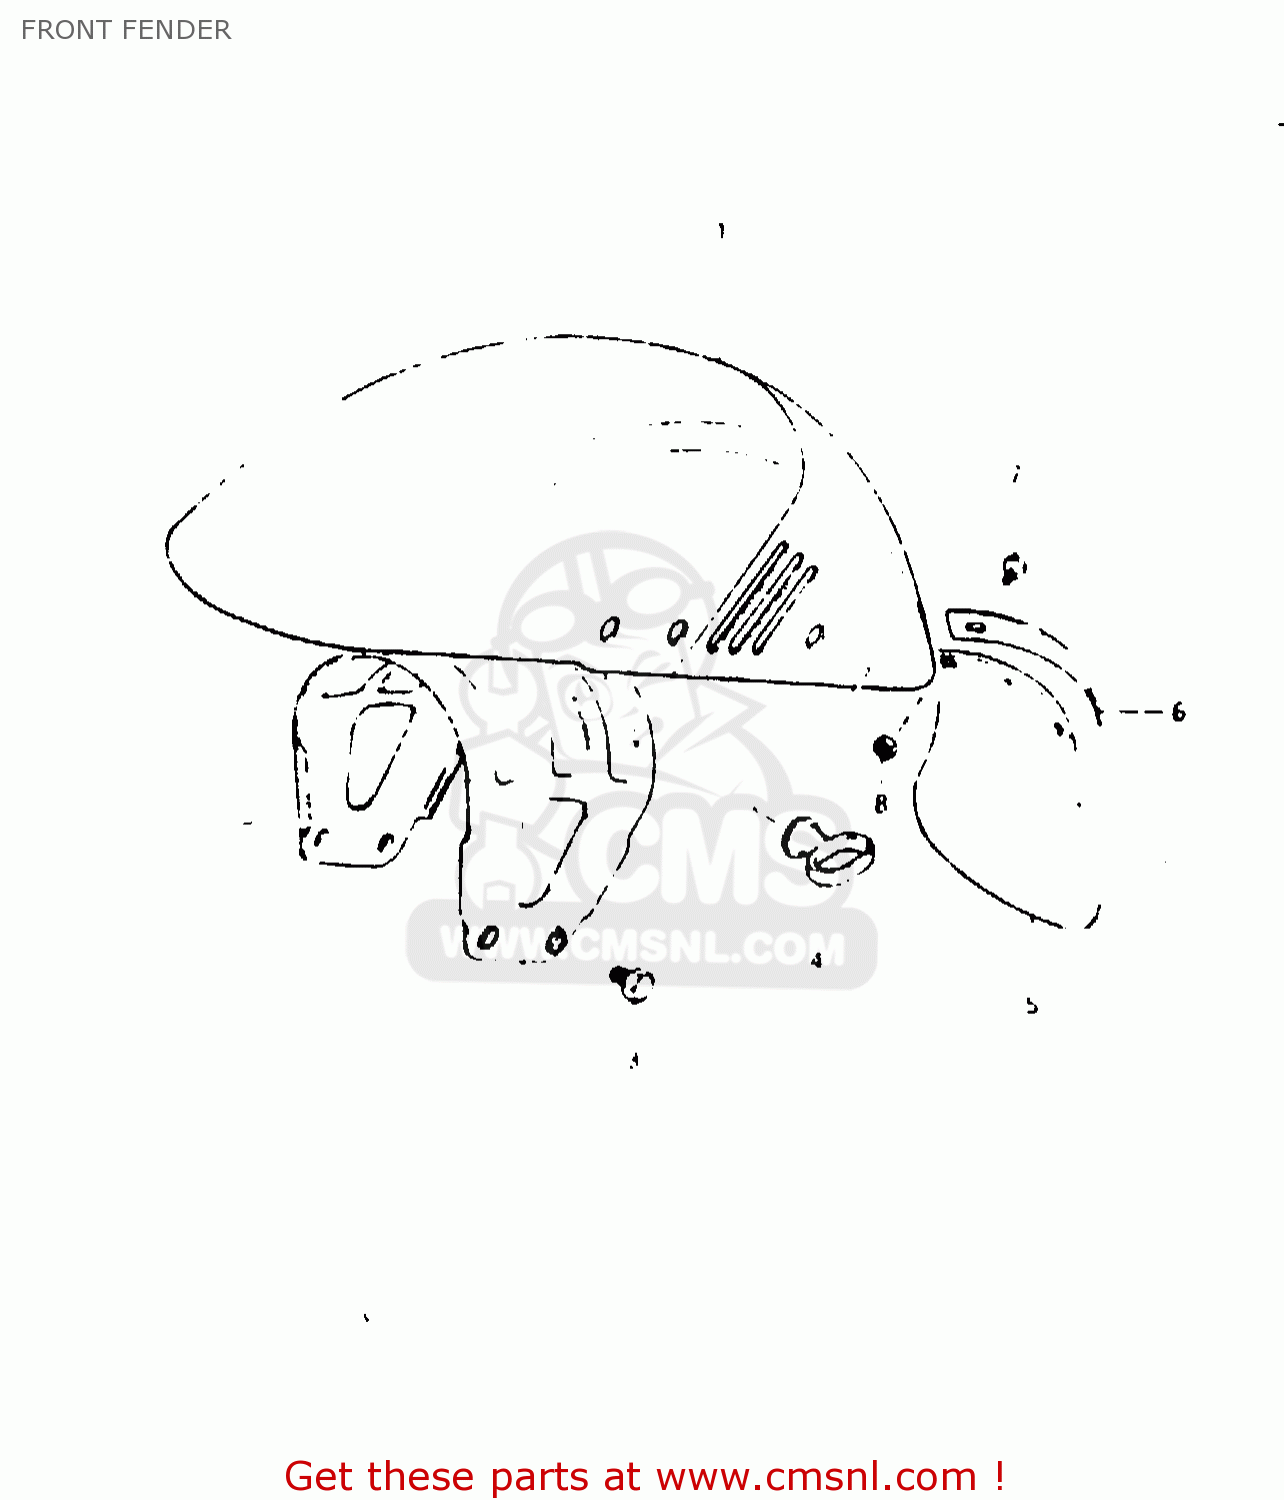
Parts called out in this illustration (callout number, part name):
1	FR FENDER
2	BRACE,FRONT FENDER
3	BOLT 8X16
4	GUIDE,CABLE
